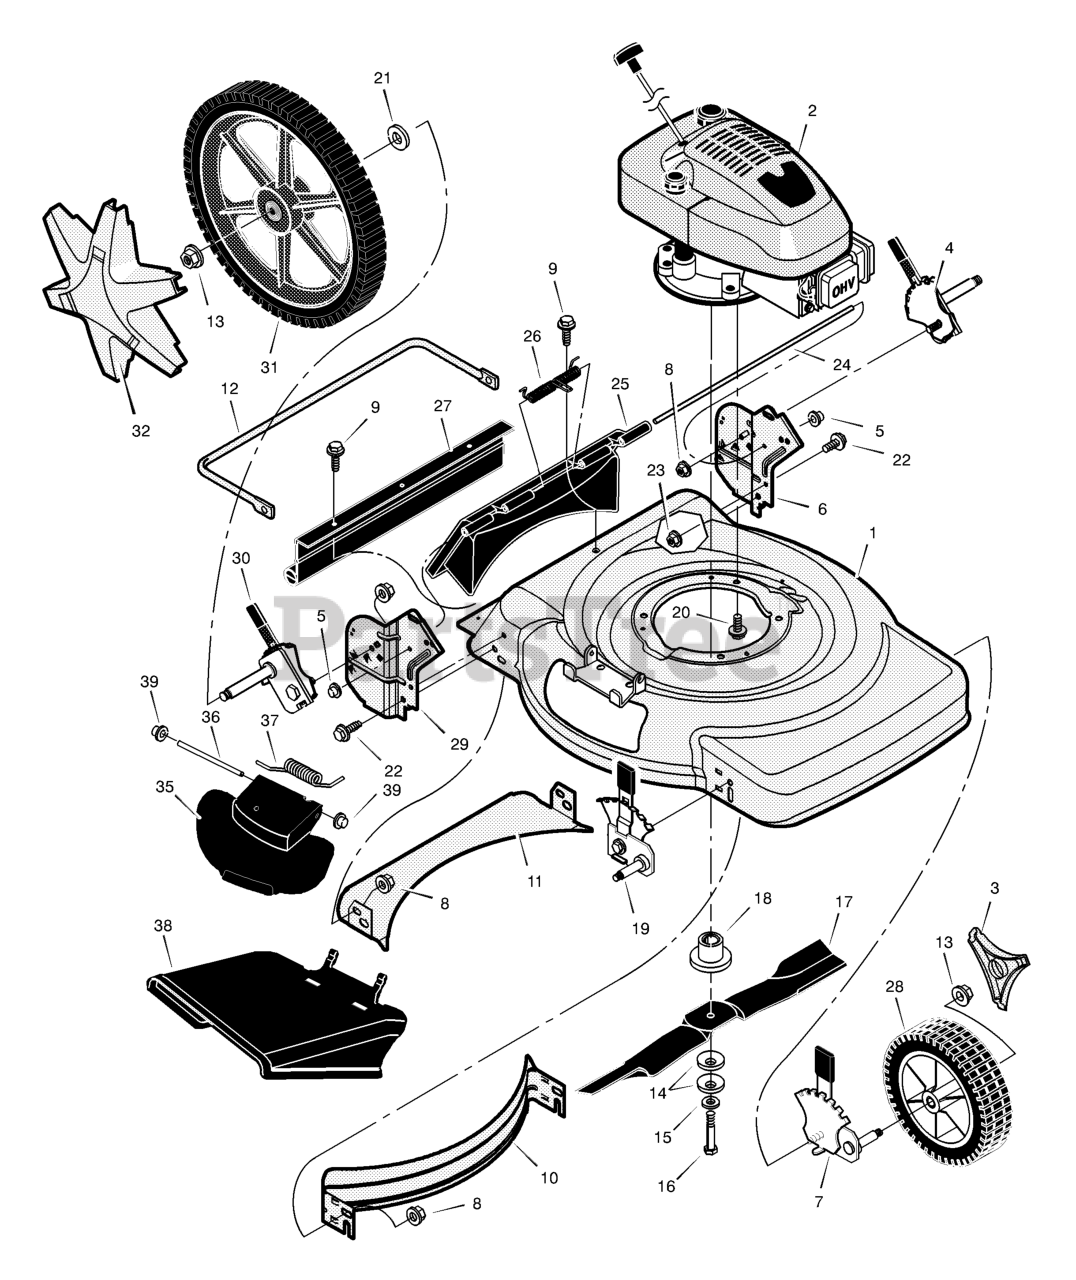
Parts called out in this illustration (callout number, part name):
2	Engine
3	Cap, Hub
4	Adjuster, Left Rear Height
5	Push On Cap
6	Bracket, Left Handle
7	Adjuster, Left Front Height
8	Nut, Flange
10	Baffle, Front
11	Baffle, Rear
13	Nut, Flange
14	Washer, Belleville
18	Adapter, Blade
19	Adjuster, Right Front Height
20	Bolt, Engine
22	Bolt
23	Nut, Flange
24	Rod, Pivot
25	Door, Rear (Black)
26	Spring
27	Guard, Rear
28	Wheel & Tire, Front
29	Bracket, Right Handle
30	Adjuster, Right Rear Height
31	Wheel & Tire, Rear
32	Cap, Hub
35	Cover, Mulch (Black)
36	Rod, Pivot
37	Spring, Torsion
38	Deflector, Chute (Black)
39	Push On Cap
